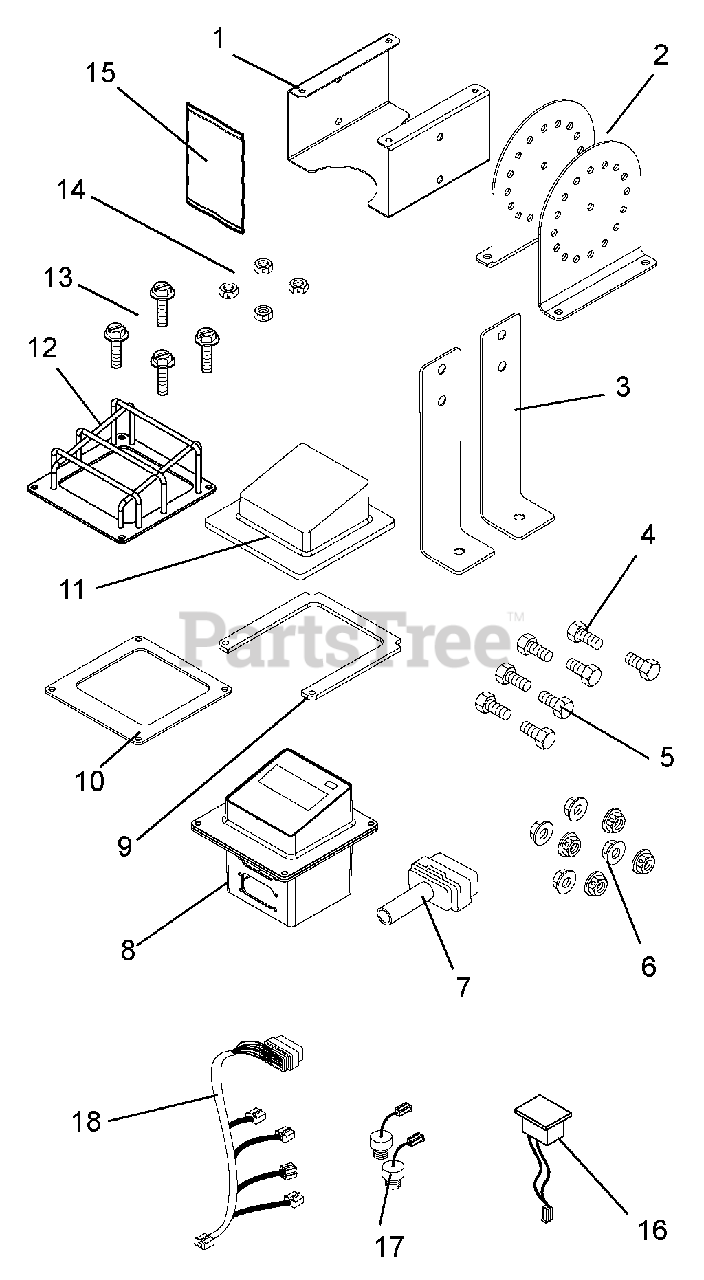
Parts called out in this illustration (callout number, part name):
1	Eye-Q(TM) Retrofit Bracket
2	Eye-Q(TM) Retrofit Leg
3	Eye-Q(TM) Retrofit Long Leg
4	1/4-20 x 1 Hex Bolt, Grade 5
5	1/4-20 x 1/2 Hex Bolt, Grade 5
6	1/4-20 Top Locking Flange Nut
7	Eye-Q(TM) Retrofit Harness
8	Eye-Q(TM) 2006
9	Mounting Enclosure Spacer
10	Eye-Q(TM) Gasket
11	Element Guard
12	Eye-Q(TM) Guard
13	10-24 x 1-1/2 Hex Washer Head Machine Screw
14	10-24 Nylon Locknut w/Insert
15	Eye-Q(TM) Owner/Operator Manual
15	Eye-Q(TM) Owner/Operator Manual -- Multilingual
16	Eye-Q(TM) Accelerometer Kit
17	Eye-Q(TM) Temperature Kit
18	Eye-Q(TM) Accessory Wire Harness
